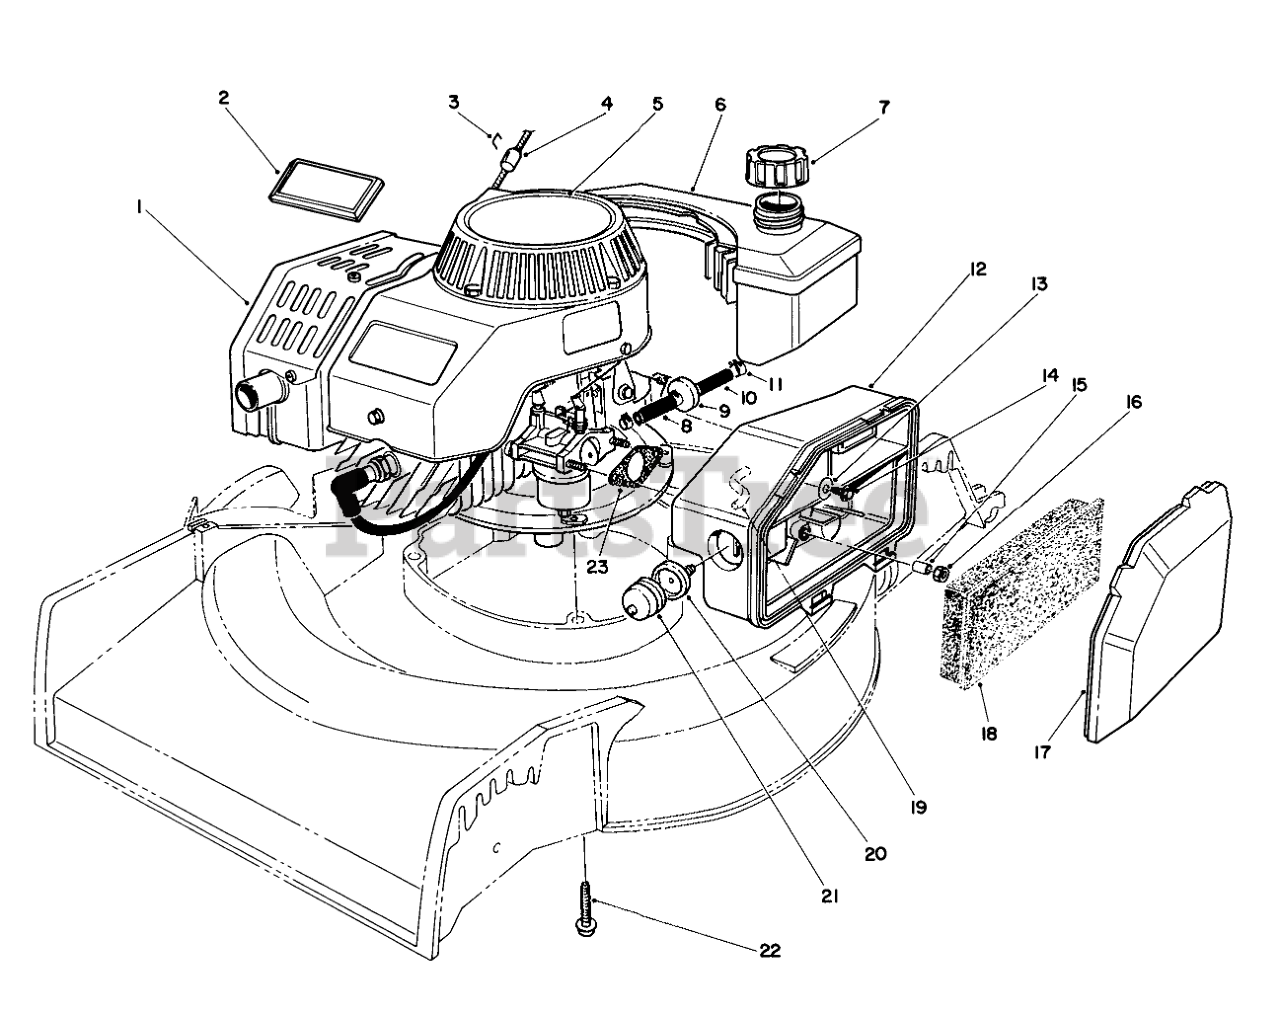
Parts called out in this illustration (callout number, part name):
1	Engine
2	TORO LOGO PLT
3	Staple
5	DECAL- 2 CYC RECOIL
6	FUEL TANK ASM
7	GAS CAP ASM
8	HOSE-FUEL
9	FILTER-FUEL
10	HOSE-FUEL
11	CLAMP-FUEL LINE
12	BODY-AIR CLEANER
13	WASHER-FLAT
14	SCREW-HH
15	SPACER
17	COVER-AIR CLEANER
18	ELEMENT-AIR CLEANER
19	HOSE-PRIMER
20	BODY-PRIMER
21	BULB-PRIMER
22	SCREW-HHF, WHIZ
23	GASKET-AIR CLEANER
